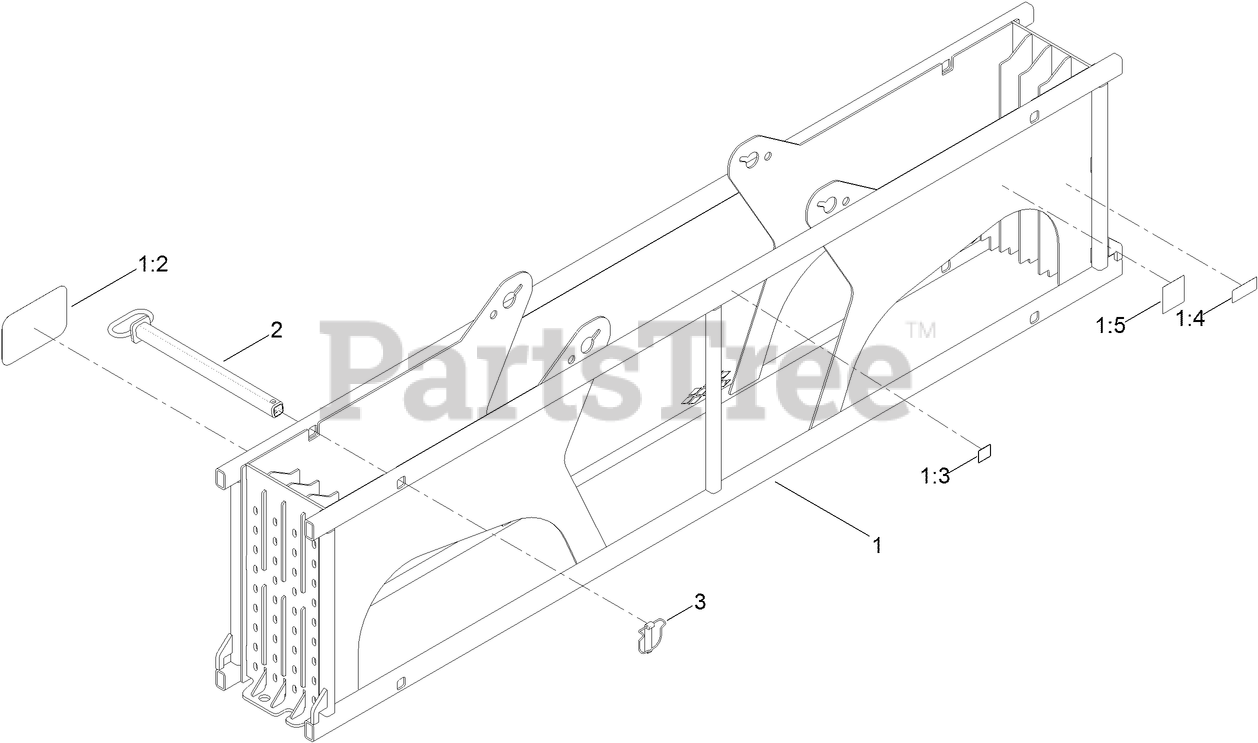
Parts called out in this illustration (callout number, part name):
1	ROD BOX ASM
1:3	DECAL-WEIGHT, ROD BASKET
1:4	DECAL-DANGER, ENTANGLEMENT
1:5	DECAL-WARNING, CRUSHING
2	PIN-ROD BOX
3	PIN-KLIK
